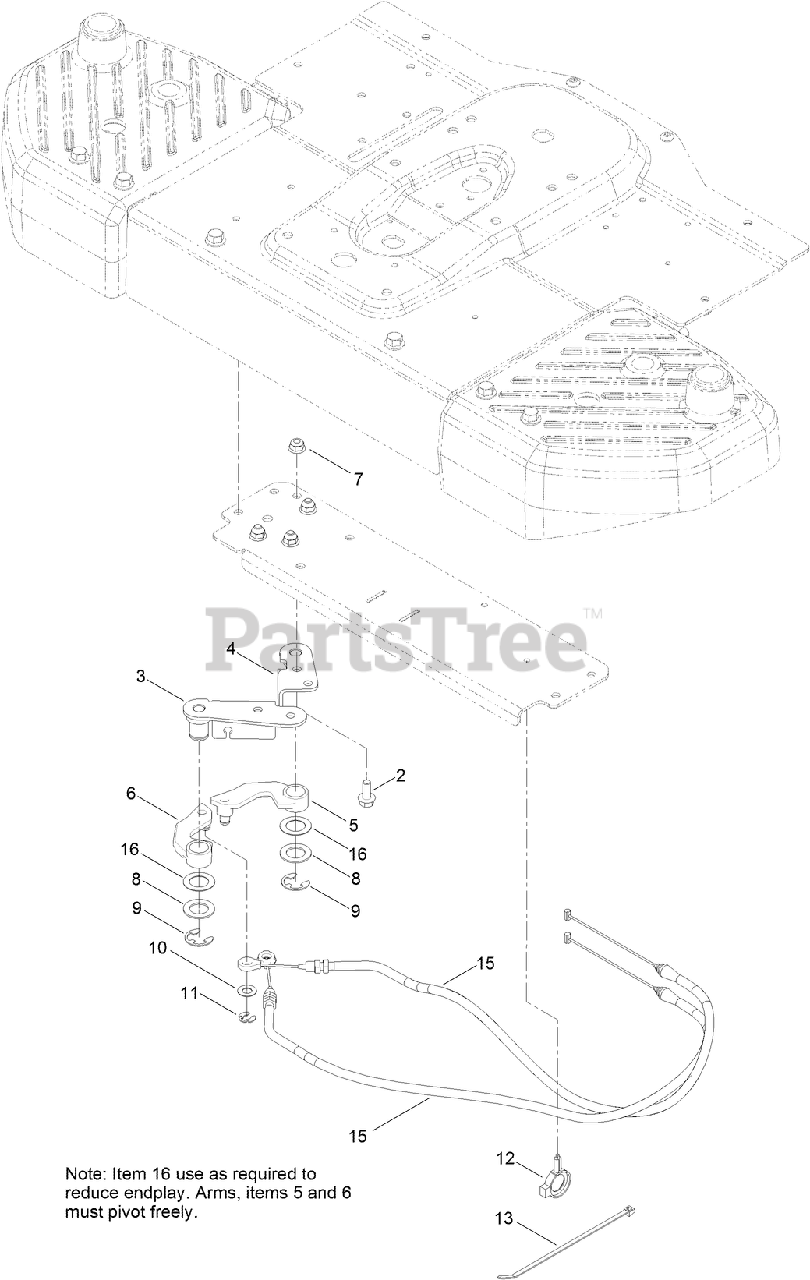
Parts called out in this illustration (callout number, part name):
2	SCREW-HHF
3	CABLE BRACKET ASM
4	CABLE BRACKET ASM
5	ARM-CABLE, RH
6	ARM-CABLE, LH
7	NUT-HF, NI
8	WASHER-THRUST
9	E-RING
10	WASHER-THRUST
11	RING-RETAINING
12	CLAMP-HOSE
13	TIE-CABLE
15	CABLE-STEERING
16	WASHER-THRUST
